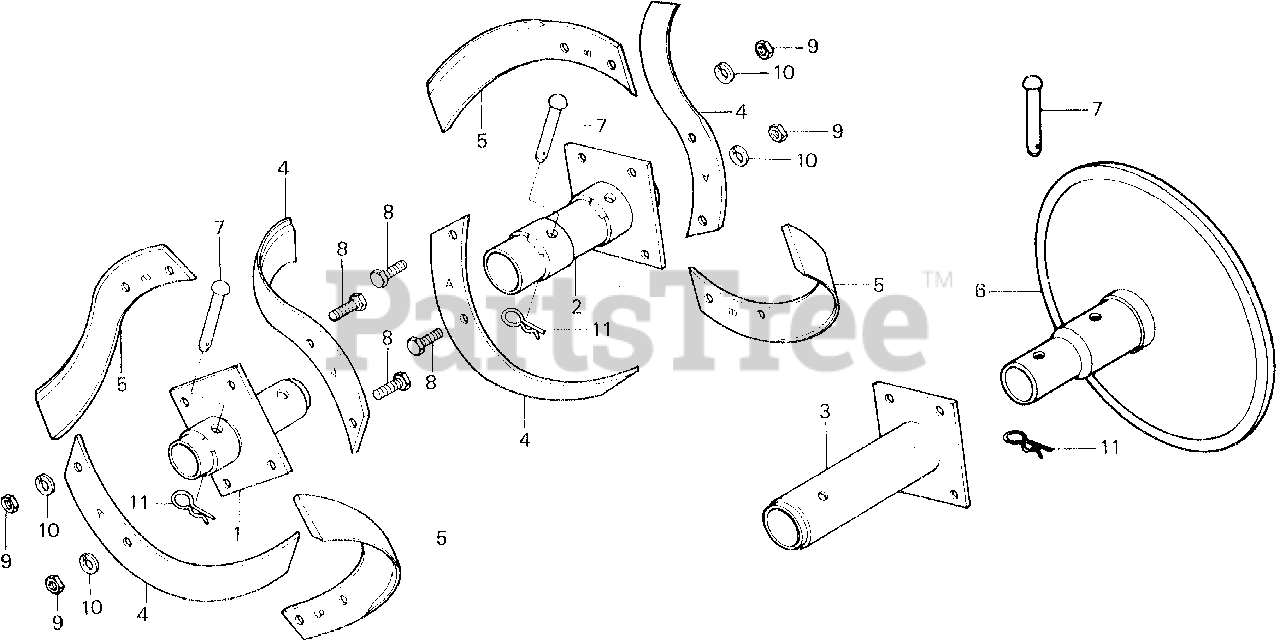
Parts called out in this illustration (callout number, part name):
1	PIPE (INNER)
2	PIPE (OUTER) (NOT AVAILABLE)
3	PIPE, EXTENSION
4	TINE A, ROTOR
4	TINE A, ROTARY
5	TINE B, ROTOR
5	TINE B, ROTARY
6	DISK, SIDE (NOT AVAILABLE)
7	PIN (10X53.5)
8	BOLT, HEX. (10X25)
9	NUT, HEX. (10MM)
10	WASHER, SPRING (10MM)
11	PIN, LOCK (10MM)
